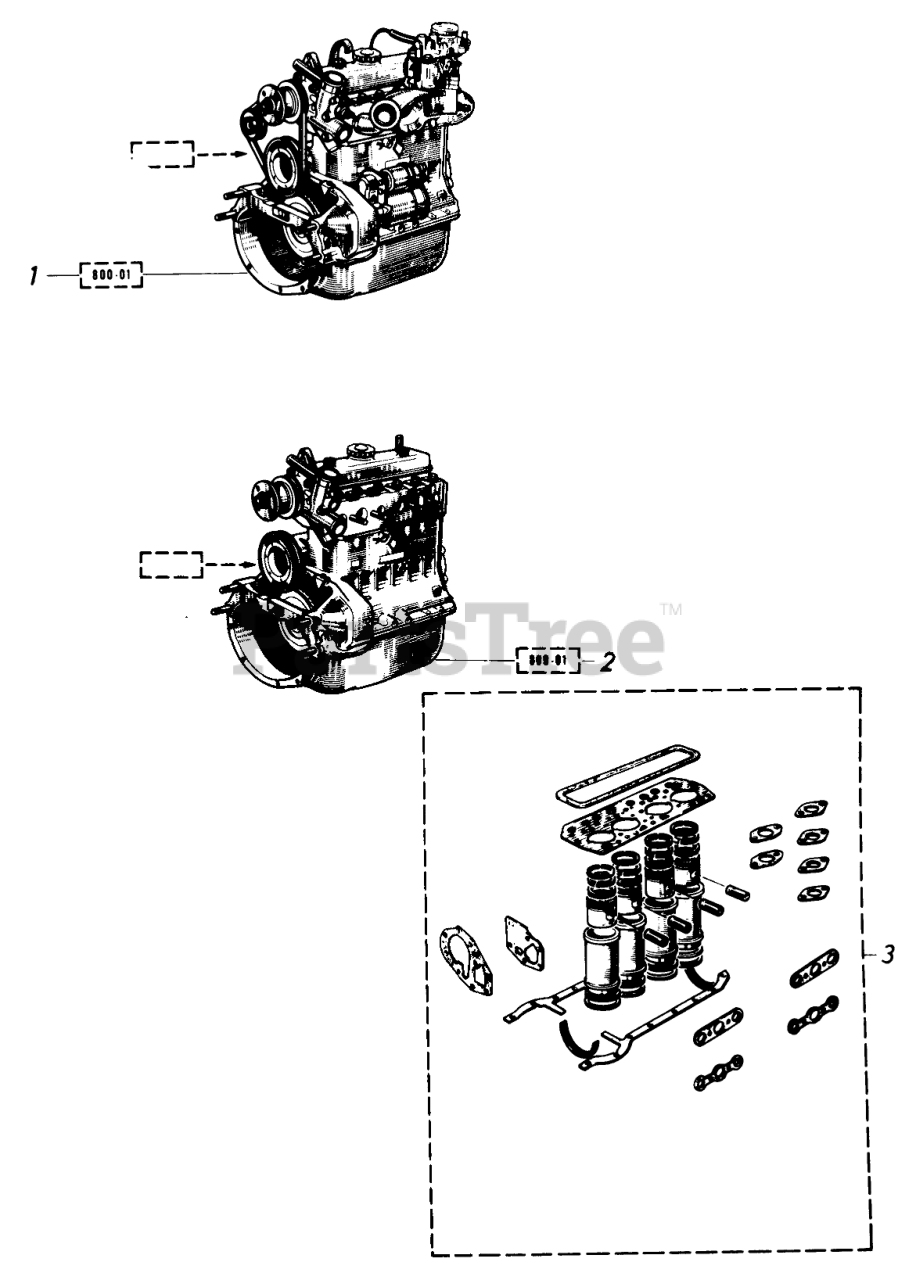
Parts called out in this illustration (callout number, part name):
1	Engine Complete
2	Engine Assy. Short Block
3	Piston Set with Gaskets
